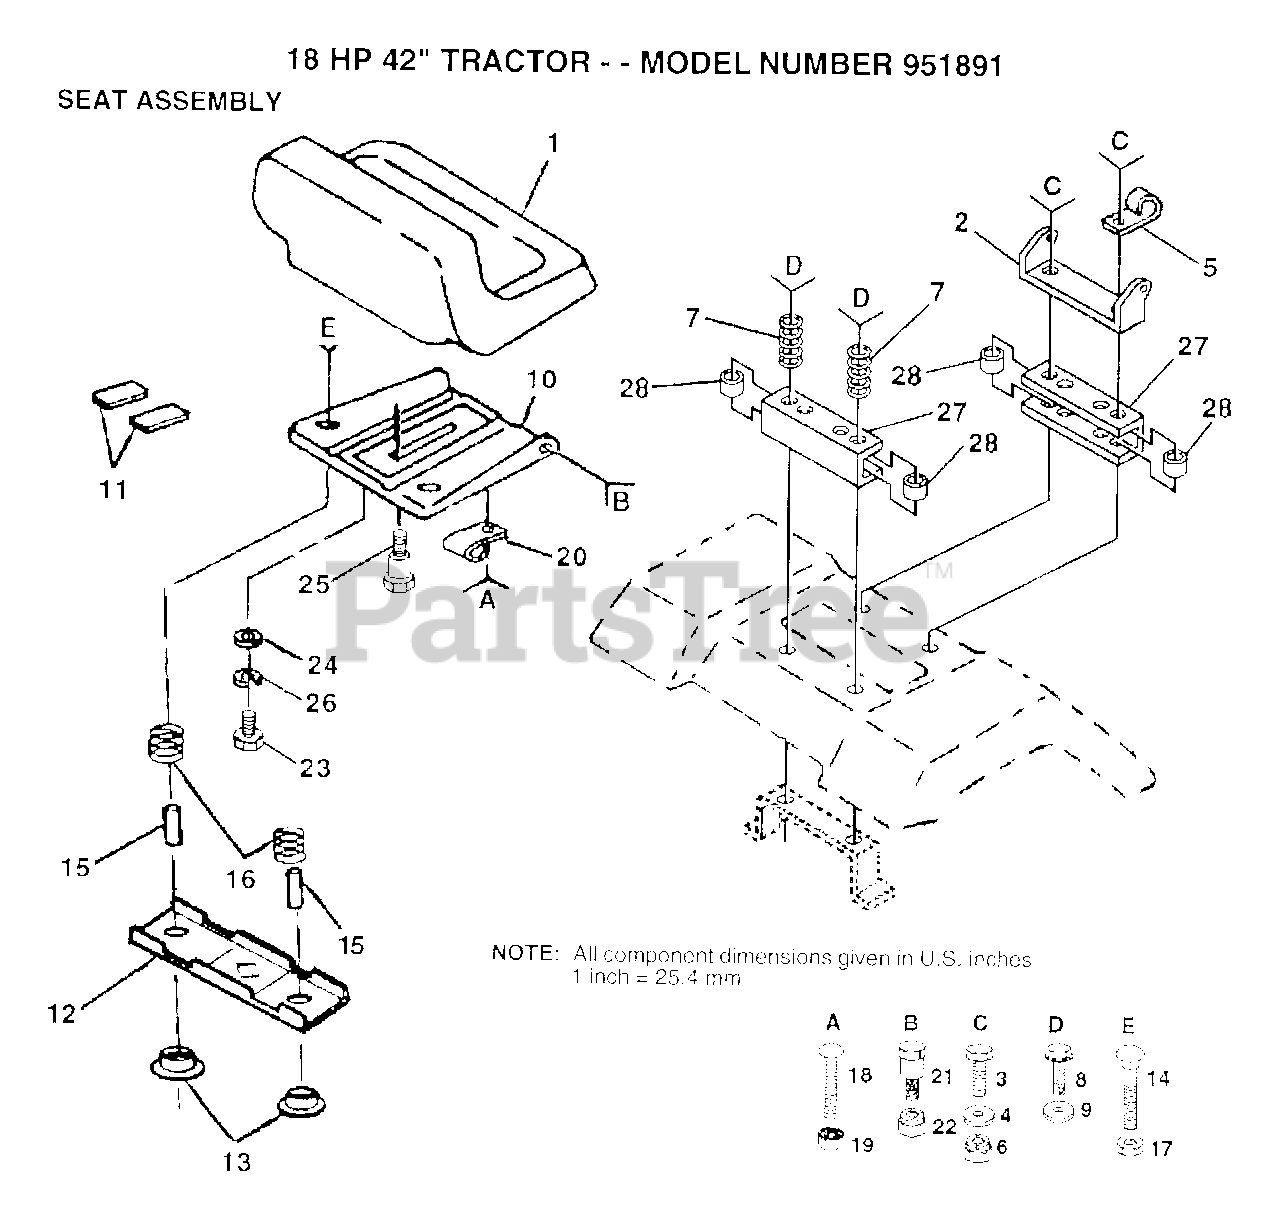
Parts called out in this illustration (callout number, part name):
3	BOLT
4	WASHER
5	CLIP T
7	SPRING COMPRESSIO
8	SCREW
9	WASHER
11	STRIP FORM
12	BRKT SWITCH
13	BUSHING
15	SPLIT SPACER
16	SPRING
19	"NUT,KEPS"
23	BOLT
24	WASHER
25	"BOLT,SHOULDER"
26	LOCKWASHER
27	SEAT SPACER
28	SPLIT SPACER
